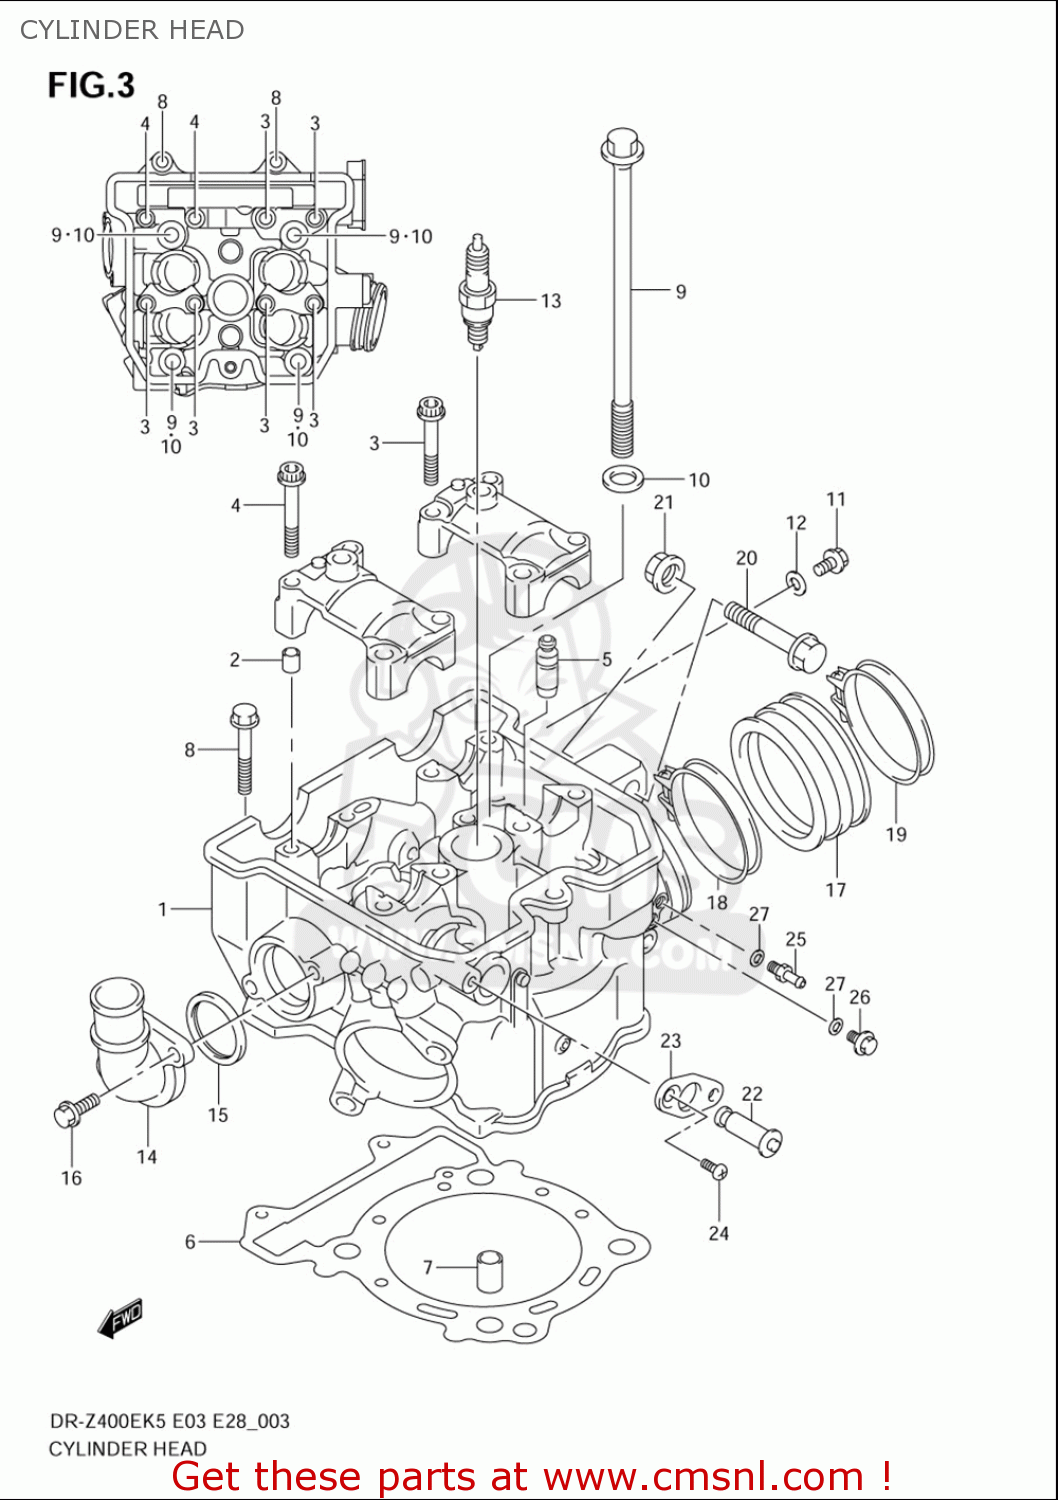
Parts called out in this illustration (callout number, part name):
1	HEAD ASSY,CYLINDER
2	PIN(6.2X8X11)
3	BOLT
5	GUIDE,VALVE
6	GASKET,CYLINDER HEAD (NAS)
7	PIN
8	BOLT(6X39)
9	BOLT(10X175)
10	WASHER(10.5X19X2)
11	BOLT
12	GASKET(5.8X13X1.2) (NAS)
13	PLUG,SPARK(CR8E)
14	COVER,THERMOSTAT
15	SEAL,THERMOSTAT COVER
16	BOLT
17	PIPE,INTAKE
18	CLAMP
19	CLAMP
20	BOLT(10X50)
21	NUT
22	PLUG,DECOMP SHAFT HOLE
23	RETAINER,DECOMP SHAFT SEAL
24	SCREW
25	UNION,INTAKE PORT
26	BOLT
27	GASKET(8.2X14X1) (NAS)
